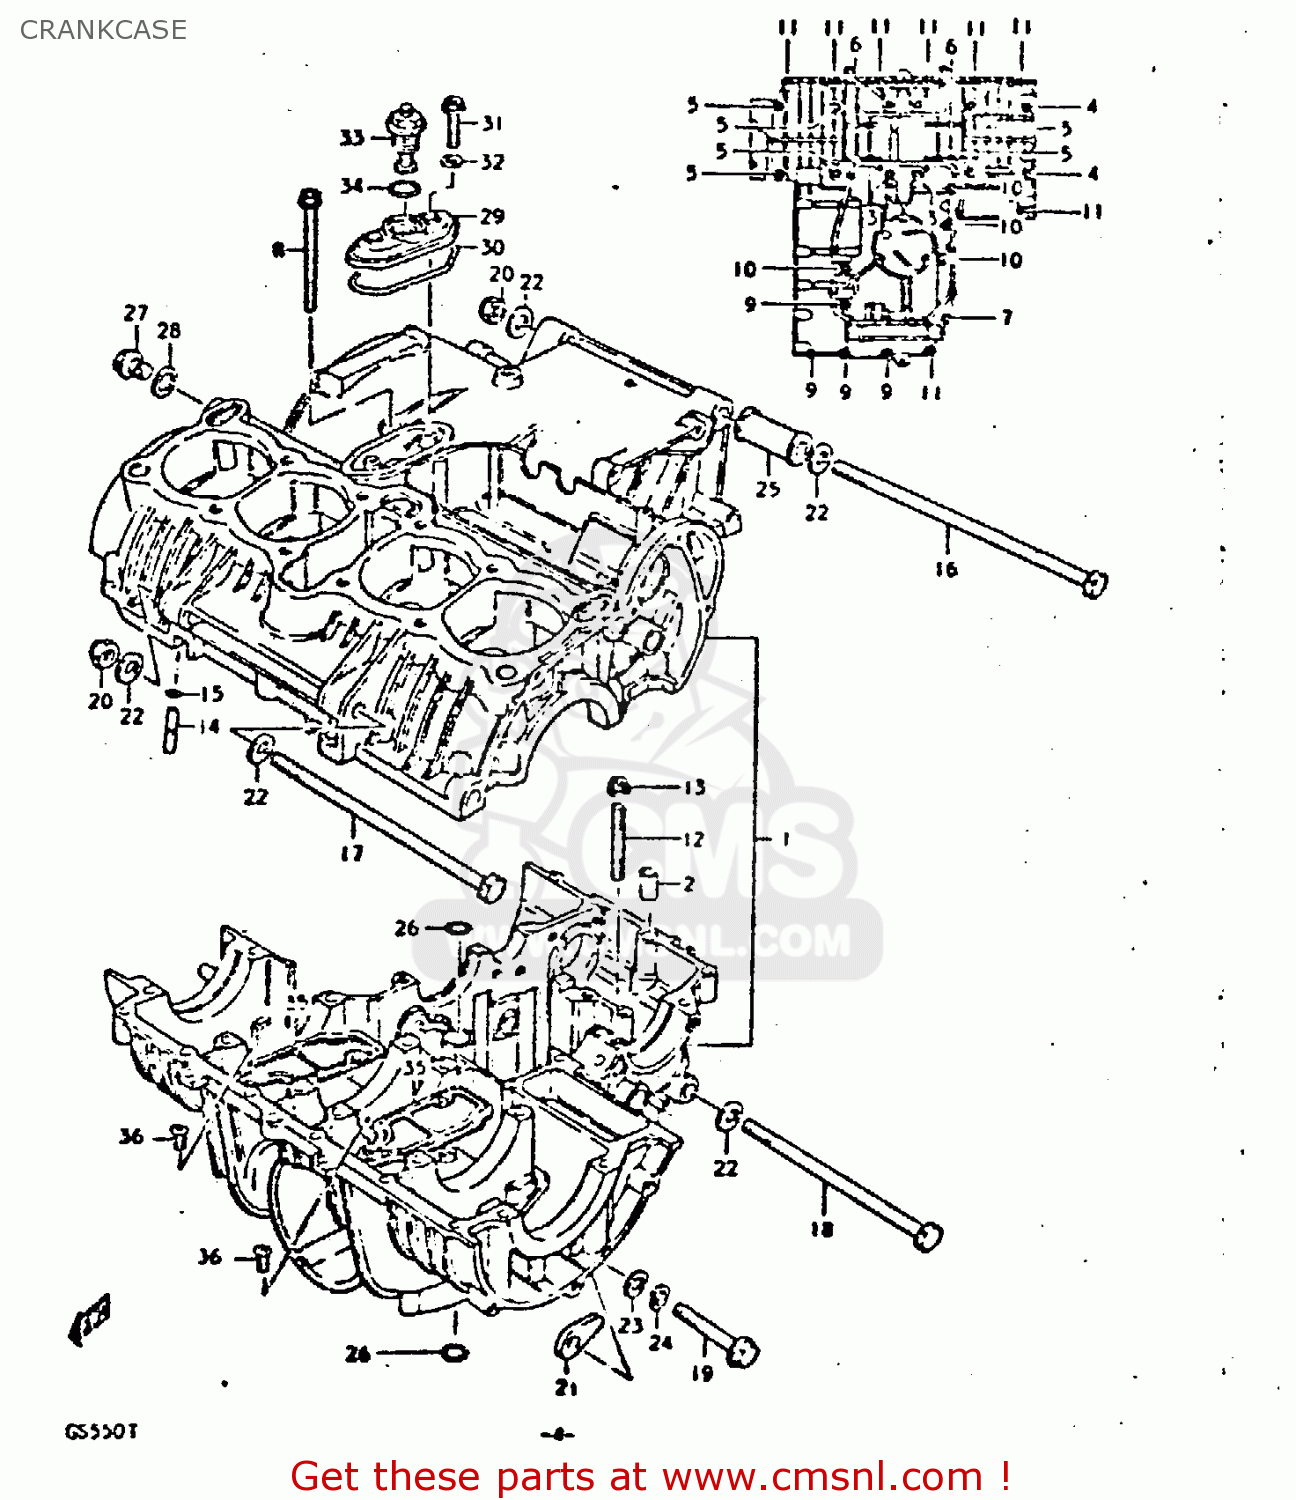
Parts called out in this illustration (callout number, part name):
1	CRANKCASE SET
2	PIN
3	BOLT
4	BOLT 8X90
5	BOLT (8X70)
6	BOLT 8X55
7	BOLT (8X45)
8	BOLT (6X90)
9	BOLT (6X60)
10	BOLT ,6X50
11	BOLT
12	STUD BOLT
13	NUT
14	UNION
15	O-RING
16	BOLT 10X270
17	BOLT
18	BOLT(10X165)
19	BOLT 10X55
20	NUT
21	NUT
22	WASHER
23	WASHER(10.5X20X3.2)
24	LOCK WASHER
25	SPACER,ENGINE MOUNT
26	O RING(D:3.2,ID:12.9)
27	PLUG (14X12)
28	GASKET(14X19.2X2) (NAS)
29	HOUSING,OIL PRESSURE SWITCH
30	O RING,PRESSURE SWITCH HOUSING
31	BOLT
32	GASKET (NAS)
33	SWITCH ASSEMBLY
34	O RING
35	PLATE,OIL SEPARATOR
36	SCREW
